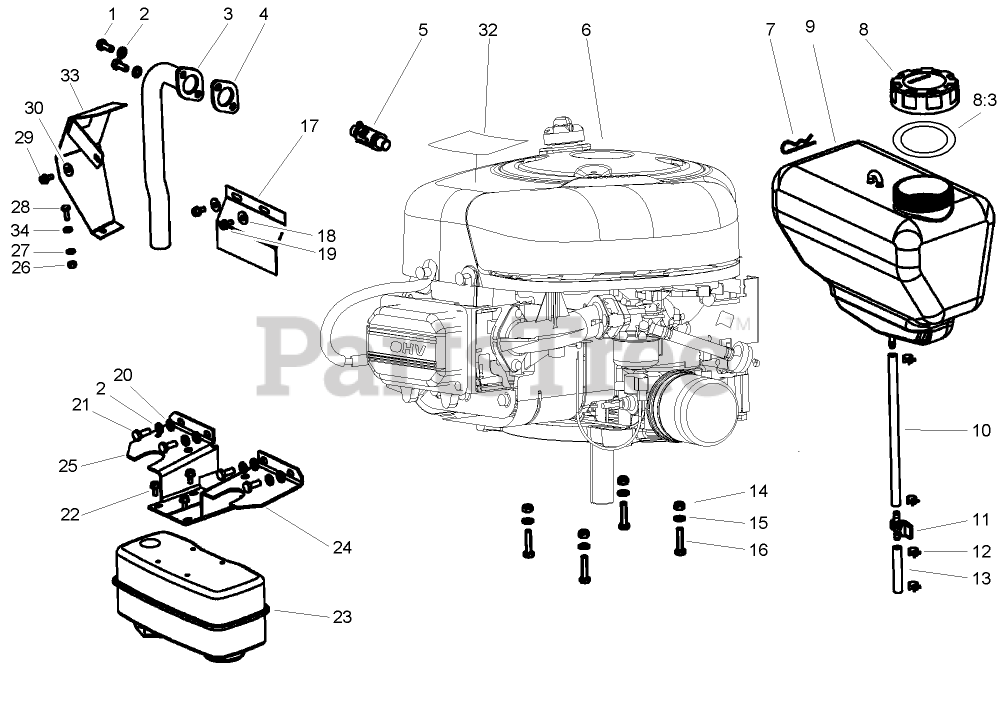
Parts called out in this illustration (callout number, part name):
1	SCREW-HH
3	TUBE-EXHAUST
4	GASKET-EXHAUST
5	VALVE-OIL DRAIN
6	Loose Parts Package
7	PIN-HAIR
8	GAS CAP ASM
8:3	GASKET-CAP, GAS
9	TANK-FUEL
10	LINE-FUEL
11	VALVE-TANK, FUEL
12	CLAMP-LINE, FUEL
13	LINE-FUEL
14	NUT-LOCK, NI
15	WASHER-PLAIN
16	SCREW-HH
17	COVER-FRONT
18	WASHER-FLAT
20	WASHER-PLAIN
21	SCREW-HH
23	MUFFLER
24	GUARD-MUFFLER, LH
25	GUARD-MUFFLER, RH
26	NUT-HEX
27	WASHER-SPRING
28	SCREW-HH
30	WASHER-FLAT
32	DECAL-ENGINE
33	Cover-Manifold, Exhaust
34	WASHER-FLAT
